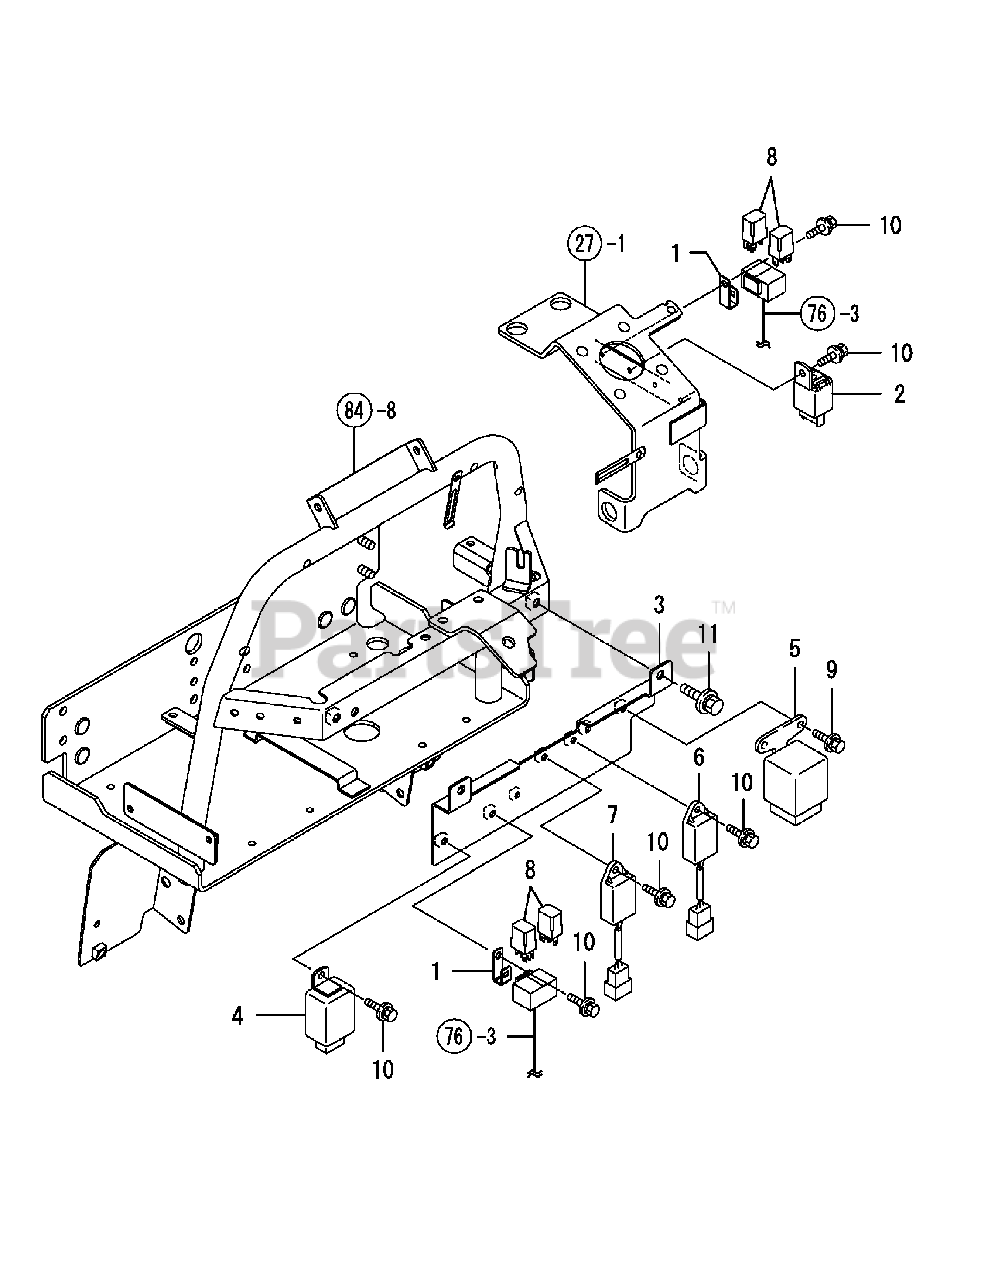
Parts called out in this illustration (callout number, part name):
2	Relay, Starter
3	Stay Cmp, Regulator
5	Relay, Glow Plug
6	Timer, Glow Plug 15 Sec
7	Timer, Fuel Solenoid 1 Sec
8	Relay, Starter
